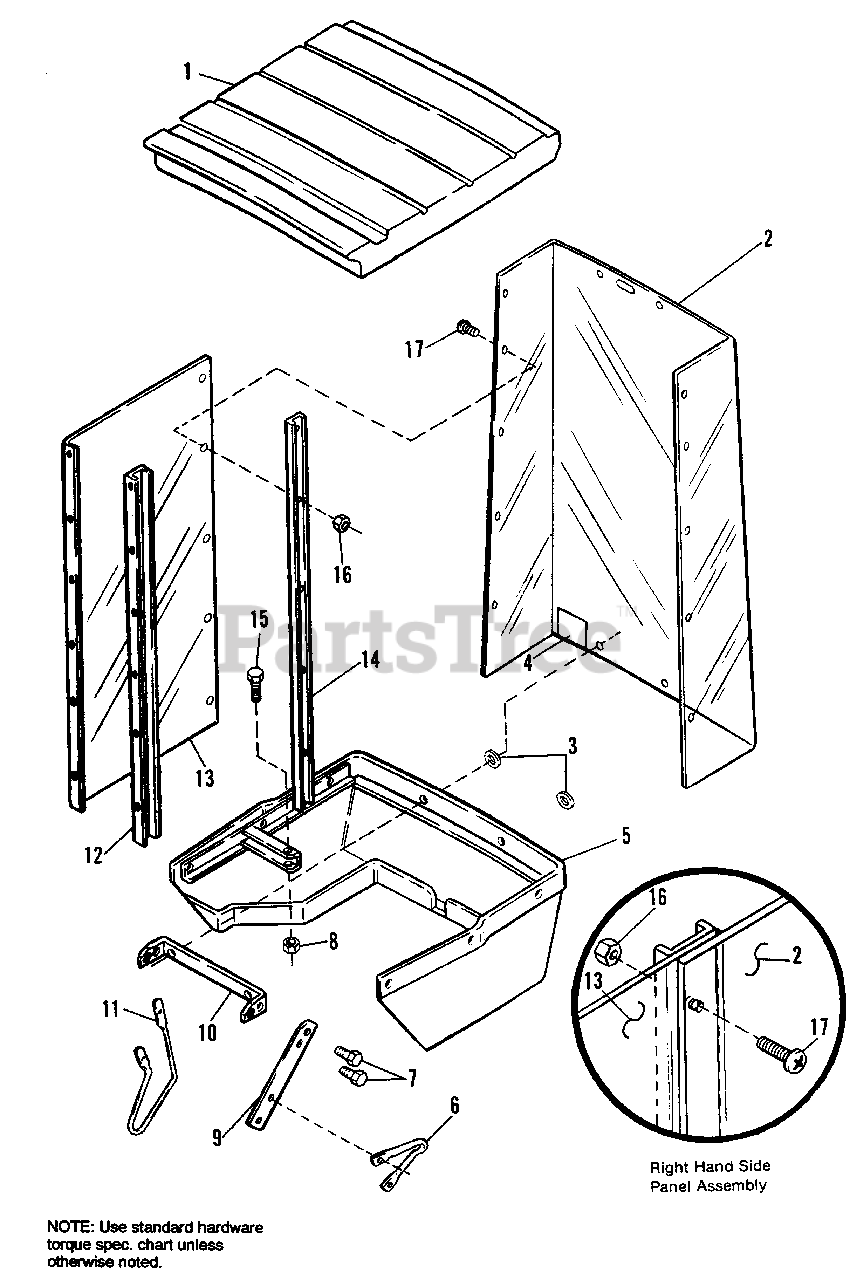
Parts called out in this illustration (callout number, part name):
1	COVER, Top
2	PANEL, Front
3	WASHER, Flat, 9/32
4	DECAL, Cleaning Instructions
5	SHROUD, Lower
6	GUIDE, Rope
7	CAPSCREW, Hex Hd., 1/4-20 x 3/4
8	LOCKNUT, Nylon, 5/16-18
9	SUPPORT, Side
10	SUPPORT, Front
11	ROD, Skid
12	CHANNEL, Side
13	PANEL, Side
14	SUPPORT ASSY., L.H.
15	CAPSCREW, Hex Hd., 5/16-18 x 1-3/4
16	LOCKNUT, Nylon, 1/4-20
17	SCREW, Phil. Truss Hd., 1/4-20 x 3/4
